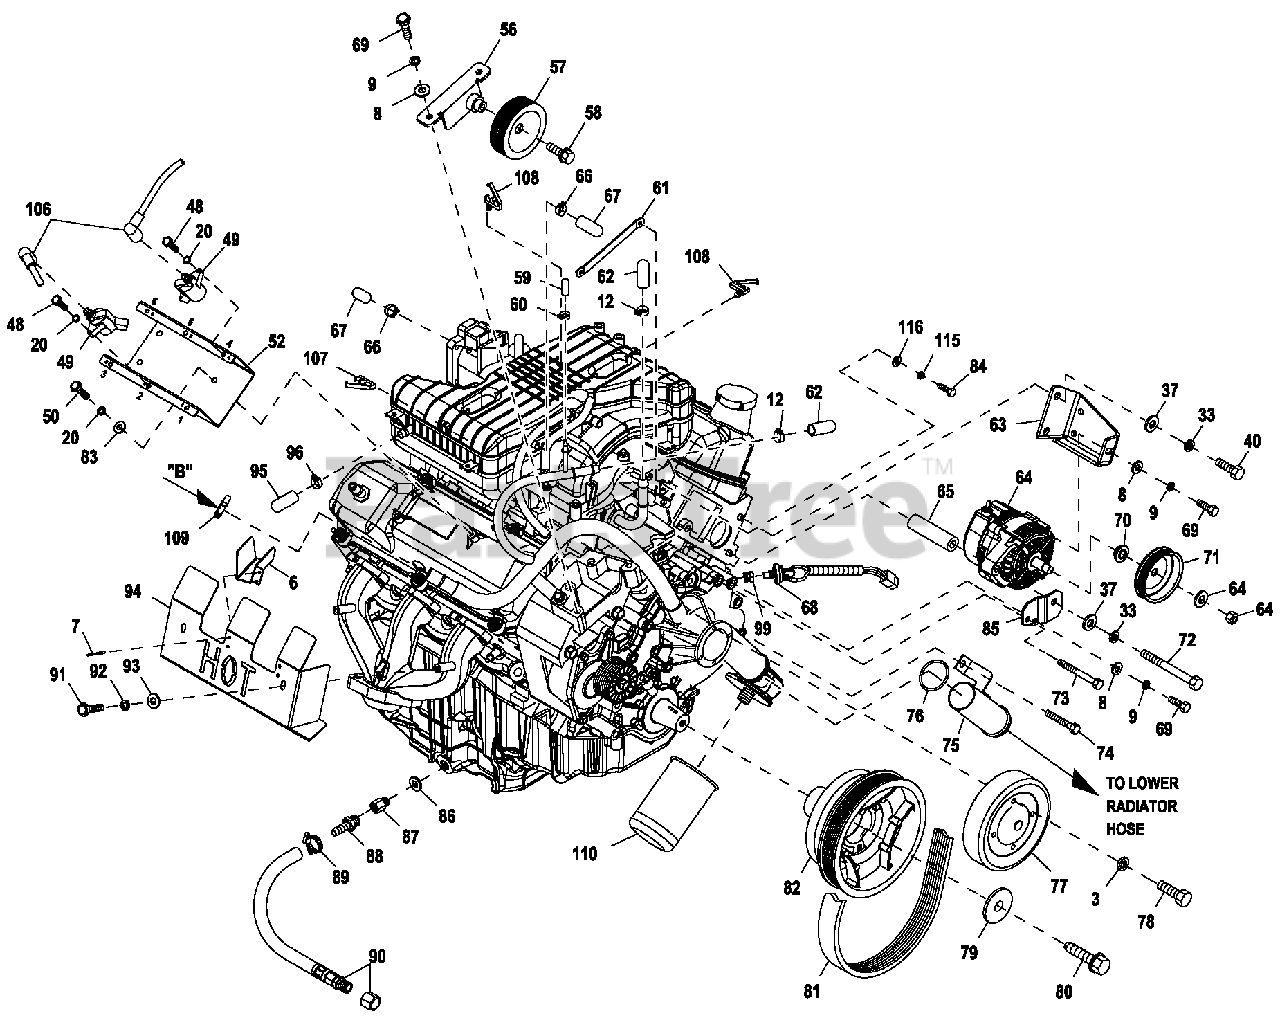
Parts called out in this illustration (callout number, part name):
3	WASHER LOC KM6-1/4
7	RIVET POP .125 X.275 SS
8	WASHER FLAT 5/16-M8 ZINC
9	WASHER LOC KM8-5/16
12	CLAMP HOSE BAND 1.0"
20	WASHER LOCK M5
33	WASHER LOC KM10
37	WASHER FLAT 3/8-M10 ZINC
40	SCREW HHC M10-1.5 X 20 C8.8
48	SCREW HHC M5-0.8 X 20 G8.8
49	IGNITION COIL ASSY
50	SCREW HHC M5-0.8 X 12 C8.8
56	WELDMENT IDLER BRAC KET4.2L
57	PULLEY GROOVED ENGINE IDLER
58	BOLT HEX FL HD M8-1.25 X 28
59	CAP ANTIFREEZE RUBBER 8.5DIA
60	CLAMP HOSE BAND .75
62	CAP ANTIFREEZE 5/8"ID X 1,2"LG
63	BRACKET DC ALTERNATOR L H 4.2L
64	ALTERNATOR DC W/OUT PULLEY
65	SPACER ALTERNATOR 4.2L G3
66	CLAMP H OSE BAND .50
67	CAP VINYL 3/8"IDX1"DP BLK
68	HARN LOW OIL PRESS SWITC H ASSY
69	SCREW H H C M8-1.25 X 25 C8.8
70	SPACER DC ALTERNATOR PULLEY
71	PULLEY 117 OD DC ALTERNATOR
72	SCREW H H C M10-1.5 X 160 C8.8
75	TUBE COOLANT LOWER RADIATOR
76	O-RING 1-1/2" X 1-3/4" X 1/8"
77	PULLEY WATER PUMP 4.2L
78	SCREW HHC M6-1.0X1 2 G8.8
79	SPACER 46.5 O.D. X 15 I.D. X 5 THK.
81	BELT SERPENTINE 71.04"
82	HARMONIC BALANCER REWORK 4.2L
83	WASHER FLAT M5
84	SCREW HHC M5-0.8 X 10 C8.8
85	BRACKET DC ALTERNATOR RH 4.2L
86	WASHER NYLON .50 X .87 X .06
87	ADAPTER M12-1.75 X 3/8NPT
88	BARBED STR 3/8NPTX3/8
89	CLAMP HOSE .38-.87
90	HOSE OIL DRAIN ASSY 21"
91	SCREW HHC M6-1.0X 12 SS
92	WASHER LOCK 1/4-M6 SS
93	WASHER FLAT 1/4 SS
94	HEAT SHIELD EXH 4.2L RH
95	CAP VINYL .5"IDX 1.0"DP BLK
96	CLAMP HOSE BAND .63
99	BSHG RDCR HEX 1/4 TO 1/8
106	SPARK PLUG WIRE SET 4.2L
107	RETAINER SPARK PLUG WIRE - LOOSE TYPE
108	RETAINER SPARK PLUG WIRE - ATTACHED TYPE
109	CLAMP HOSE #10 .56-1.06
110	OIL FILTER 1.6.2.5.3.0.4.2L G3
115	WASHER LOCK M5
116	WASHER FLAT M5
